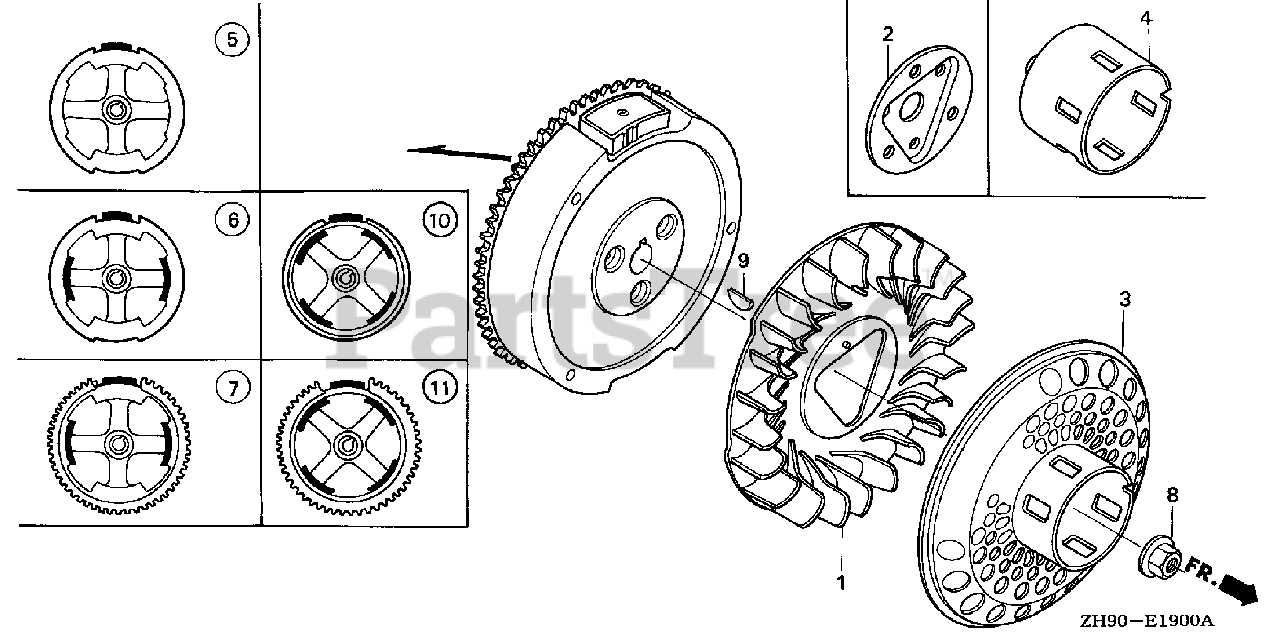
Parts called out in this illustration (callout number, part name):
1	FAN, COOLING
4	PULLEY, STARTER
5	FLYWHEEL
8	NUT, SPECIAL (16MM) (1)
9	KEY, SPECIAL WOODRUFF (25X18)
